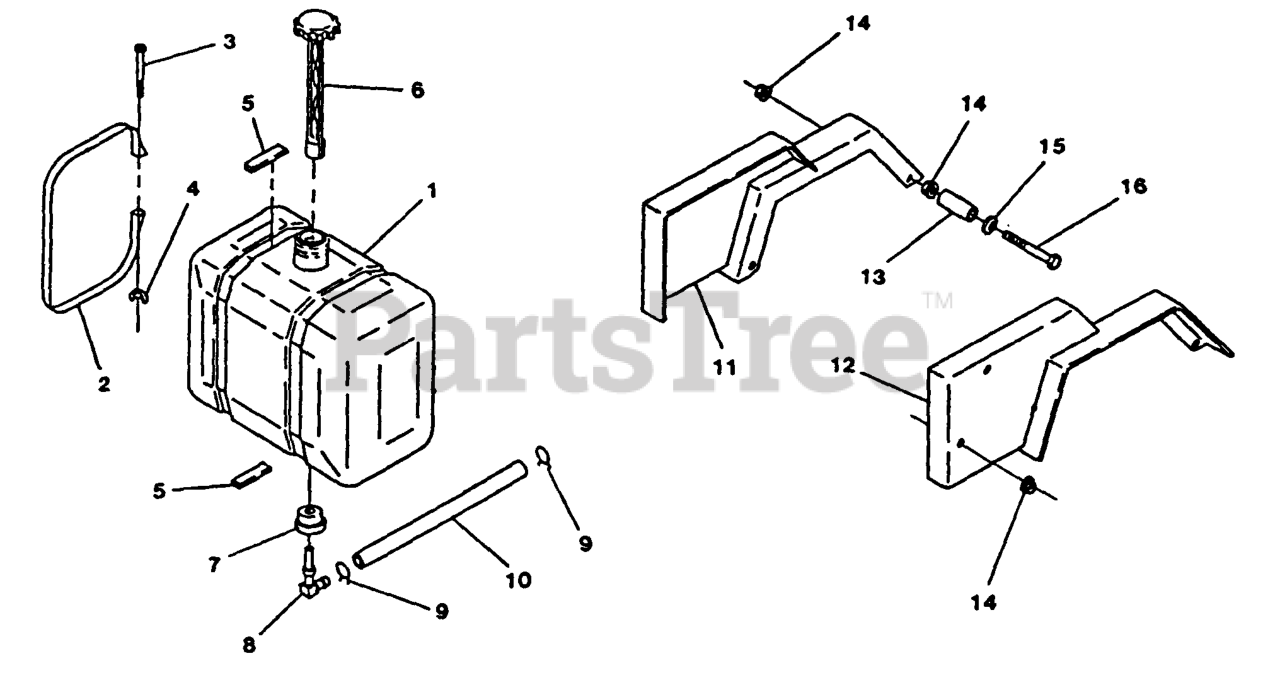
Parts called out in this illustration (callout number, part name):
4	WINGNUT
5	PAD,PLASTIC TANK
9	CLAMP
13	SPACER-FENDER
